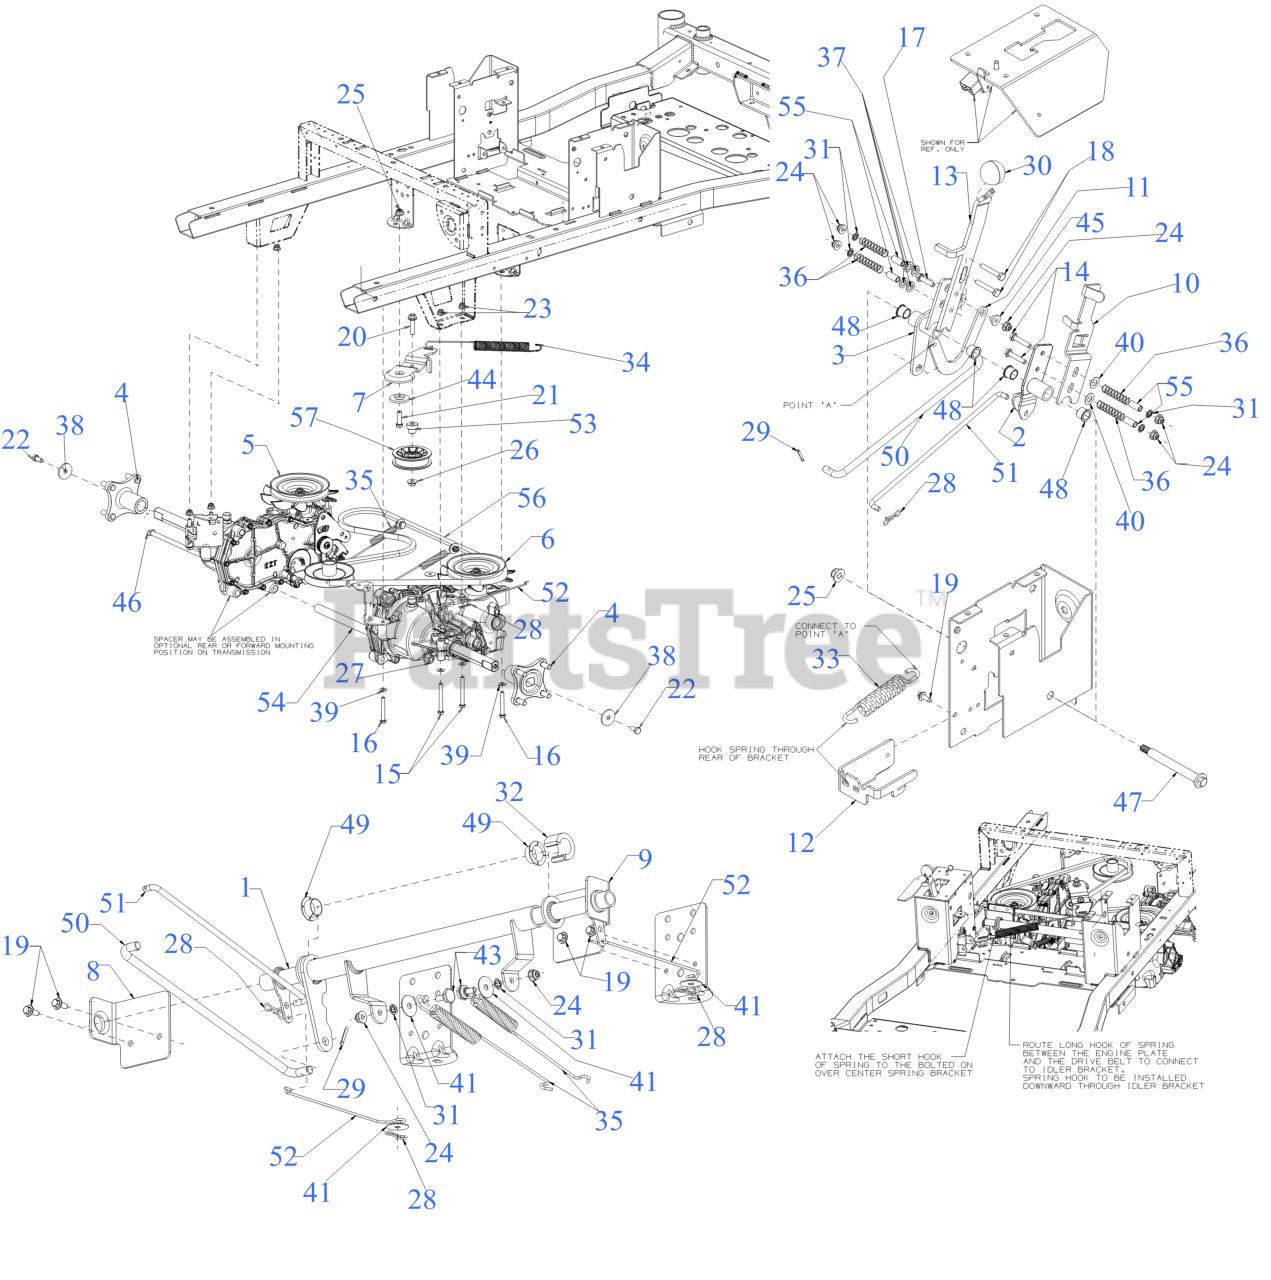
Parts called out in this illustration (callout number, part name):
1	BRAKE PIVOT SHAFT
2	BYPASS LEVER PIVOT ARM
3	PARK BRAKE PIVOT ARM
4	WHEEL HUB ASSEMBLY
5	TRANSMISSION (LH)
6	TRANSMISSION (RH)
7	HYDRO DRIVE IDLER BRACKET
8	BRAKE SHAFT SUPPORT (RH)
9	BRAKE SHAFT SUPPORT (LH)
10	TRANSMISSION BYPASS LEVER
11	OVER CENTER LINK
12	SPRING MOUNTING BRACKET
13	PARK BRAKE LEVER
14	HEX SCREW 1/4-20 x 1.25
15	HEX SCREW 5/16-18 x 2.75
16	HEX SCREW 5/16-18 x 2.25 GR5
17	SCREW 1/4-20 X1.00 GR5
18	SCREW 1/4-20 x 1.50 GR.5
19	SCREW M6-1 x .625
20	HEX HEAD BOLT (3/8-16:1.50 GR8)
21	SCREW 3/8-16 x 1.25 GR5
22	SCREW 3/8-16 x .75 GR 5
23	FLANGE LOCK NUT 5/16-18
24	FLANGE LOCK NUT
26	FLANGE LOCK NUT
27	FLANGE LOCK NUT
28	BOW TIE COTTER PIN 1/4-5/16
29	COTTER PIN
30	PARK BRAKE BALL KNOB
31	RETAINER-BOLT .25ID x .50OD
32	SPACER: .76ID x .75
33	EXTENSION SPRING .57 x 5.38
34	EXTENSION SPRING .75 DIA X 10.27
35	EXTENSION SPRING .60 DIAx8.69
36	COMPRESSION SPRING
37	FLAT WASHER
38	FLAT WASHER .390x1.500x.134
39	FLAT WASHER
40	WASHER THRUST .375X.70X.030
41	FLAT WASHER
43	SHOULDER SCREW
44	SHOULDER SPACER
45	SHOULDER SPACER
46	SUPPORT TUBE ROD
47	SHOULDER SCREW .491x3.937 3/8-16
48	FLANGE BUSHING
49	FLANGE BEARING .75 x 1.125 x .375
50	BRAKE LINK
51	BYPASS LINK
52	HYDRO BYPASS ROD .100 DIA
53	SHOULDER SPACER
54	SUPPORT TUBE
55	SPACER .252x.350x.760
56	TRANSMISSION DRIVE BELT A x 67
57	FLAT IDLER PULLEY 3.00 OD
